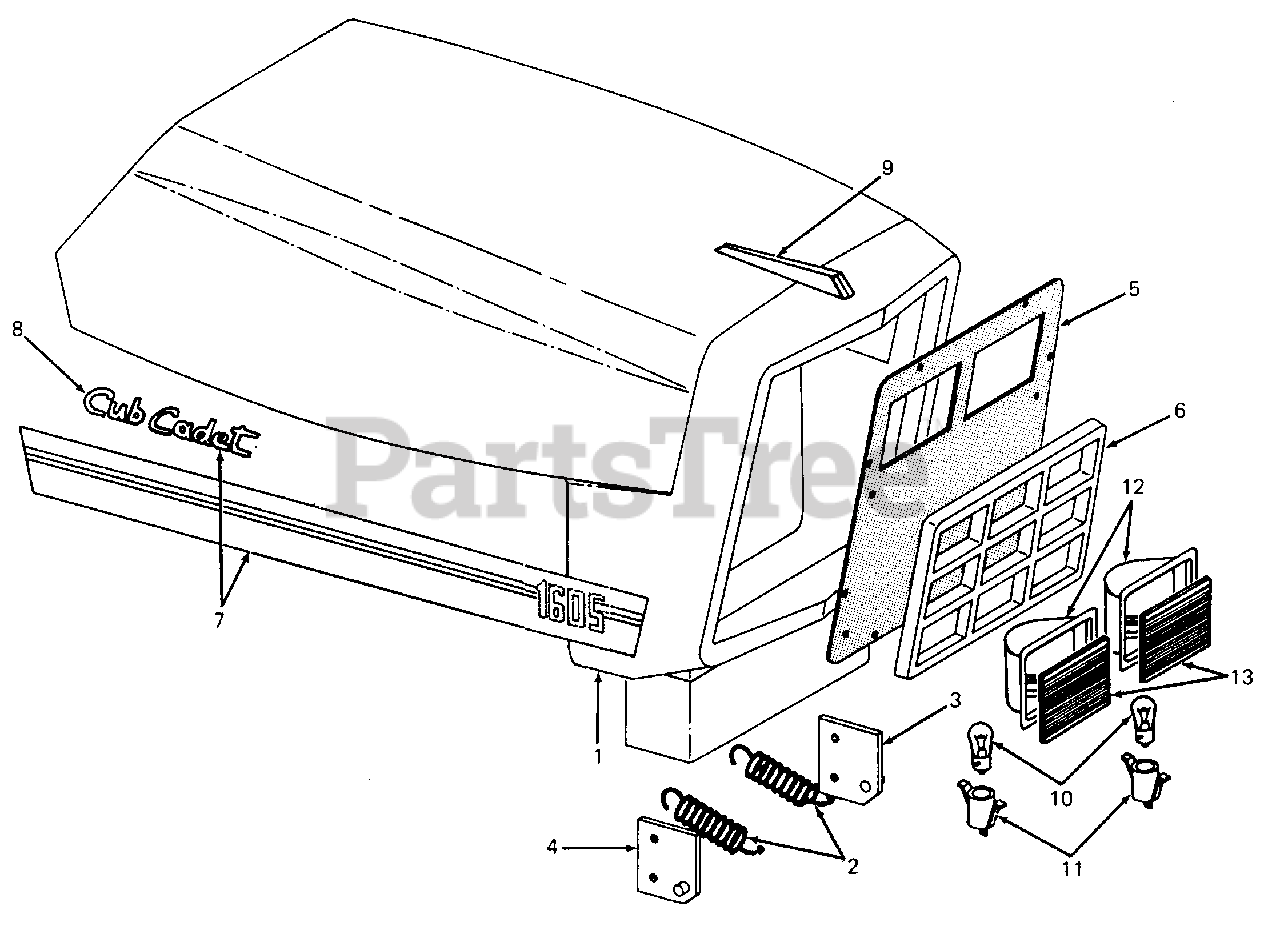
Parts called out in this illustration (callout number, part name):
1	Hood & Grille Assy
2	Spring, Extension
3	Plate, Hood LH
4	Plate, Hood RH
6	Insert, Grille
7	Graphic, Hood Decal Set
8	Graphic, Cub Cadet Script w/Adhesive
9	Ornament, Hood,
10	Bulb, 12V GE-1156
11	Socket, Twist Lock Lamp
12	Housing, Headlight
13	Lens, Sq-Headlight
